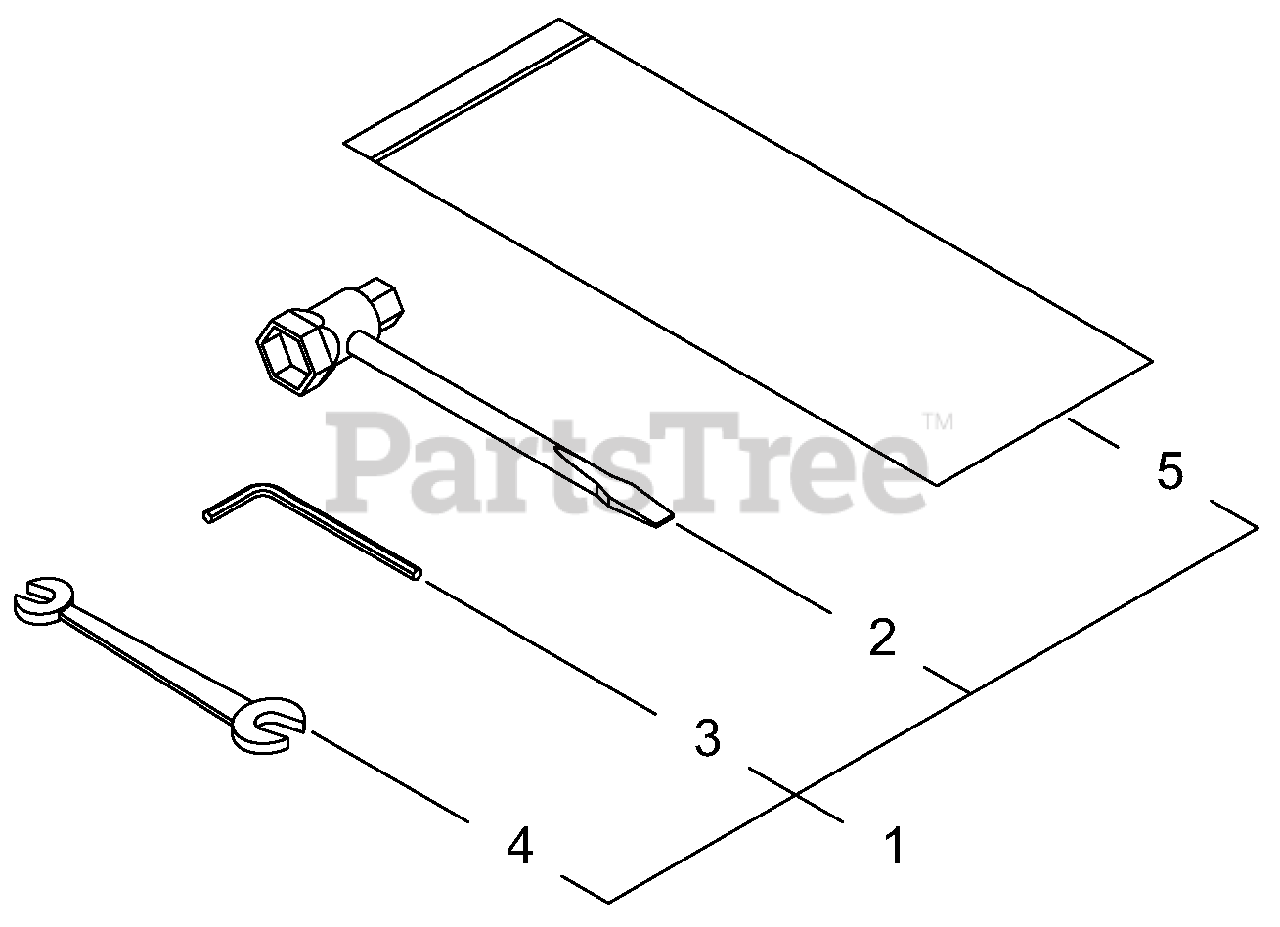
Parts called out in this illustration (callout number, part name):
1	TOOL KIT, SERVICE
2	T-WRENCH 13×19 MM
3	WRENCH, ALLEN 4 MM
4	SPANNER 8×10
5	BAG, TOOL
